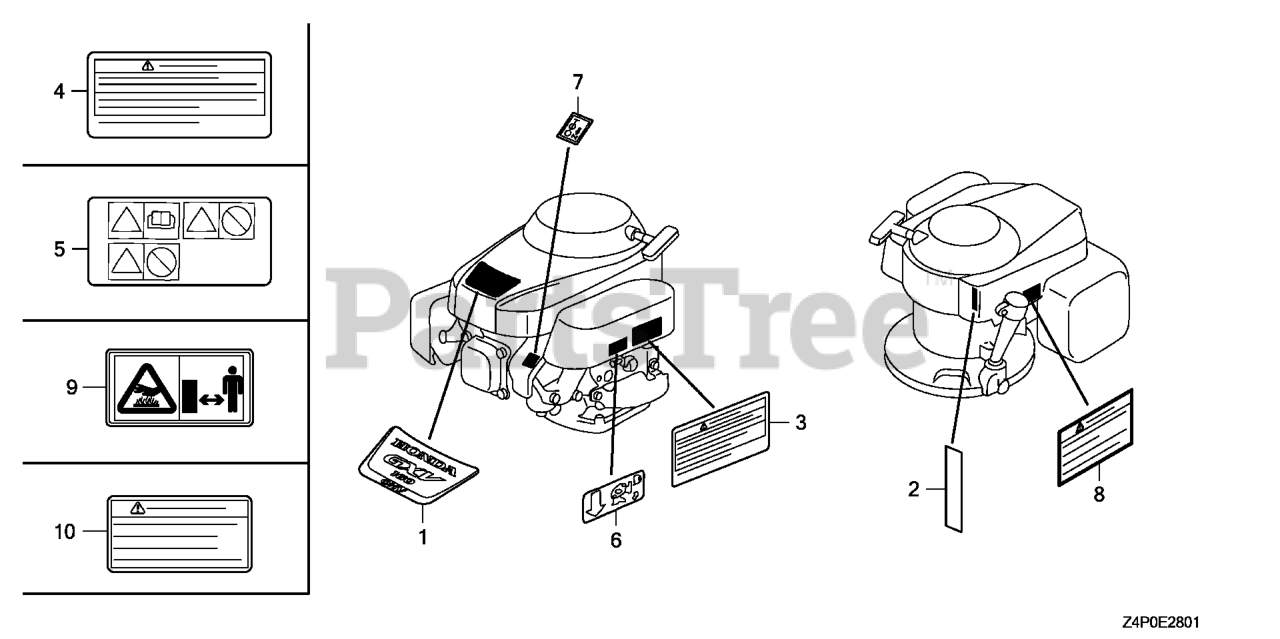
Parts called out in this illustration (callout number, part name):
1	MARK, EMBLEM (GXV160)
2	MARK, MANUFACTURER
3	MARK, OPERATOR CAUTION (CHINESE)(MADE IN CHINA)
3	MARK, OPERATOR CAUTION (ENGLISH)
4	MARK, OPERATOR CAUTION (FRENCH)
5	MARK, OPERATOR CAUTION (PICTOGRAPH)
6	MARK, FUEL PETCOCK CAUTION
8	MARK, EX. CAUTION (ENGLISH)
9	MARK, EX. CAUTION (PICTOGRAPH)
10	MARK, EX. CAUTION (FRENCH)
